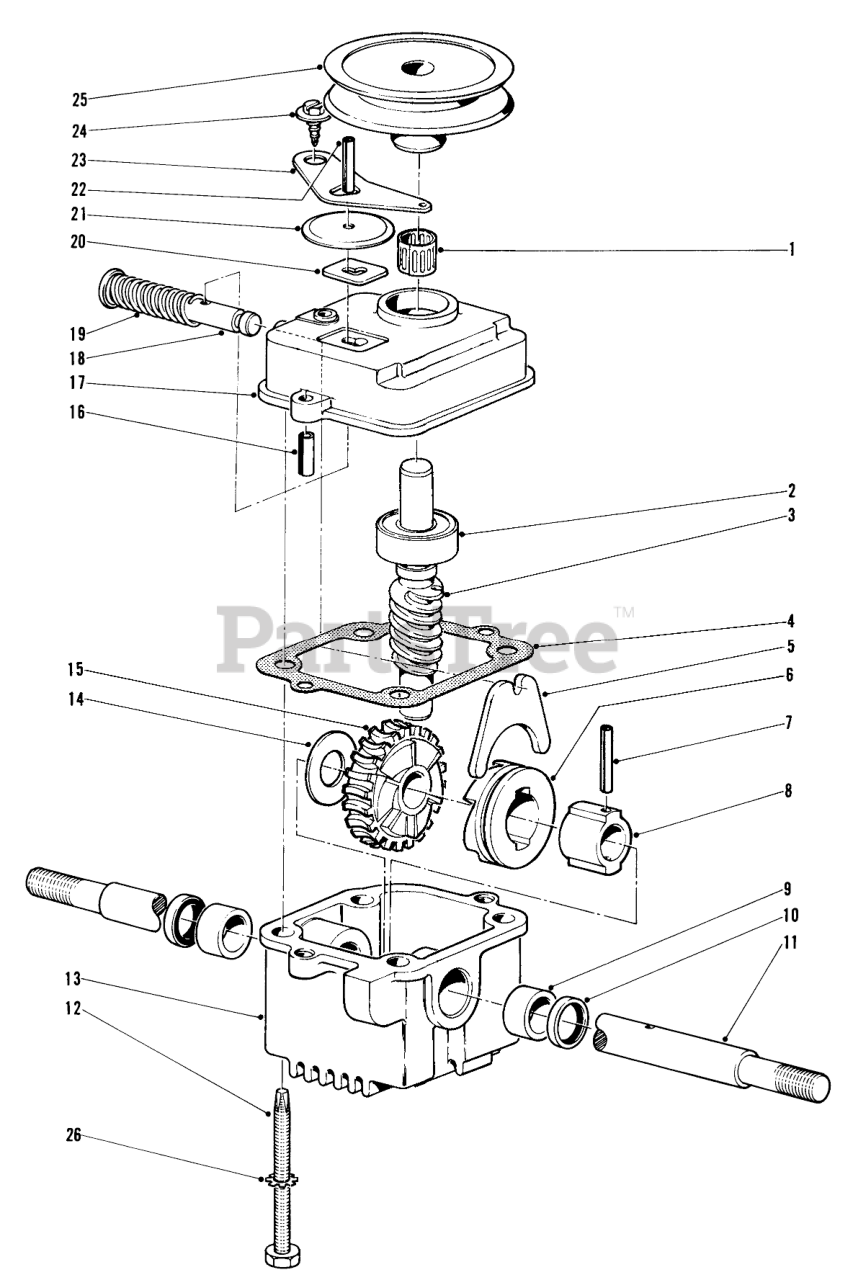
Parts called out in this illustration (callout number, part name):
1	TOLERANCE RING
2	Bearing
3	Worm Shaft
4	GASKET
5	SHIFTER FORK
6	Clutch
7	PIN-SPRING
8	SLEEVE
9	Bushing
10	Seal
11	DRIVE SHAFT
12	Sems Screw
13	Gear Case
14	THRUST WASHER
15	Worm Gear
16	3/16 X 1/2 ROLL PIN
17	GEAR CASE COVER
18	Shift Rod
19	SPRING
20	LATCH PLATE
21	TRANS DUST COVER
22	PIN-ROLL
23	SHIFTER ARM
24	Screw
25	PULLEY
26	WASHER-LOCK/EXT
